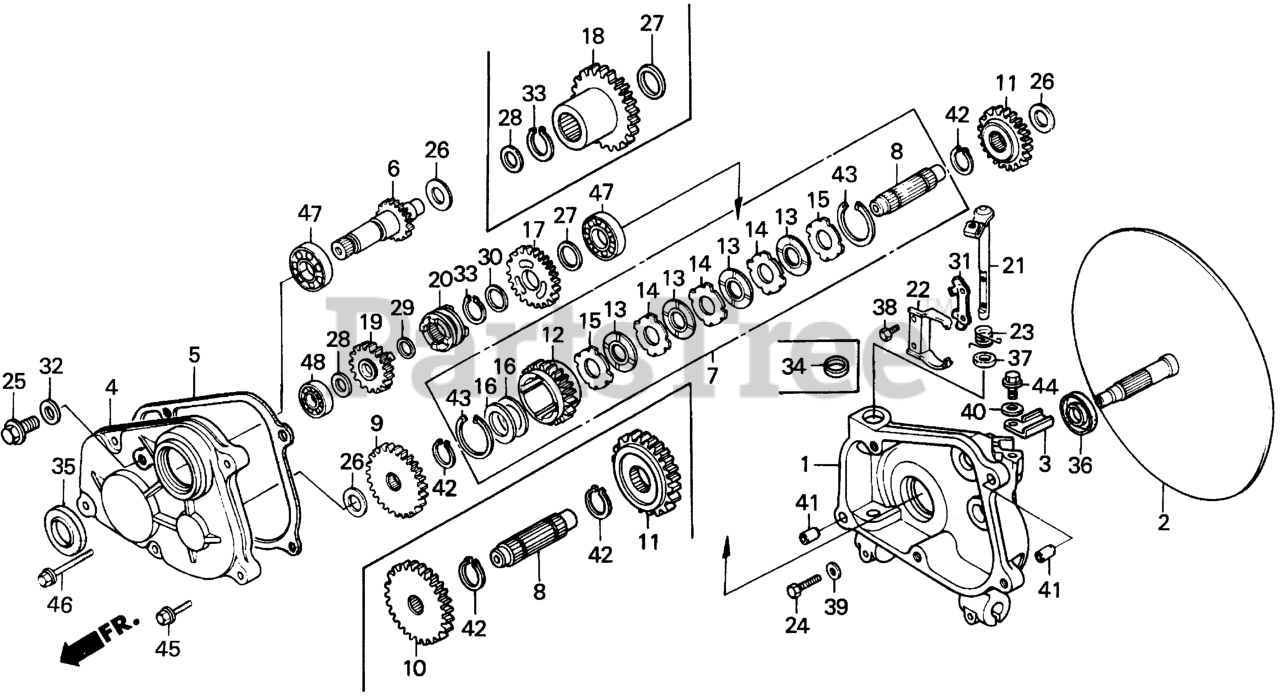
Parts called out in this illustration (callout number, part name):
1	CASE, SUB-TRANSMISSION
2	DISK, DRIVE
3	HOLDER, SUB-TRANSMISSION CABLE
4	COVER, SUB-TRANSMISSION
5	GASKET, SUB-TRANSMISSION (NOT AVAILABLE)
6	SHAFT, PRIMARY
8	COUNTERSHAFT
10	GEAR, COUNTERSHAFT FIRST (32T) (NOT AVAILABLE)
11	GEAR, COUNTERSHAFT SECOND (27T)
18	GEAR, FINAL (NOT AVAILABLE)
24	BOLT, KNOCK (6MM)
25	BOLT, DRAIN PLUG
26	WASHER (14MM)
27	WASHER (17MM)
28	WASHER (10X21)
32	WASHER, DRAIN PLUG (10.2MM)
33	CIRCLIP (OUTER) (17MM)
34	PLUG, SEALING
35	OIL SEAL (17X28X7)
36	OIL SEAL (20X32X7)
39	WASHER, PLAIN (6MM)
41	PIN A, DOWEL (8X14)
42	CIRCLIP (OUTER) (16MM)
45	BOLT, FLANGE (6X25)
46	BOLT, FLANGE (6X32)
47	BEARING, RADIAL BALL (6003)
48	BEARING, RADIAL BALL (6200)
